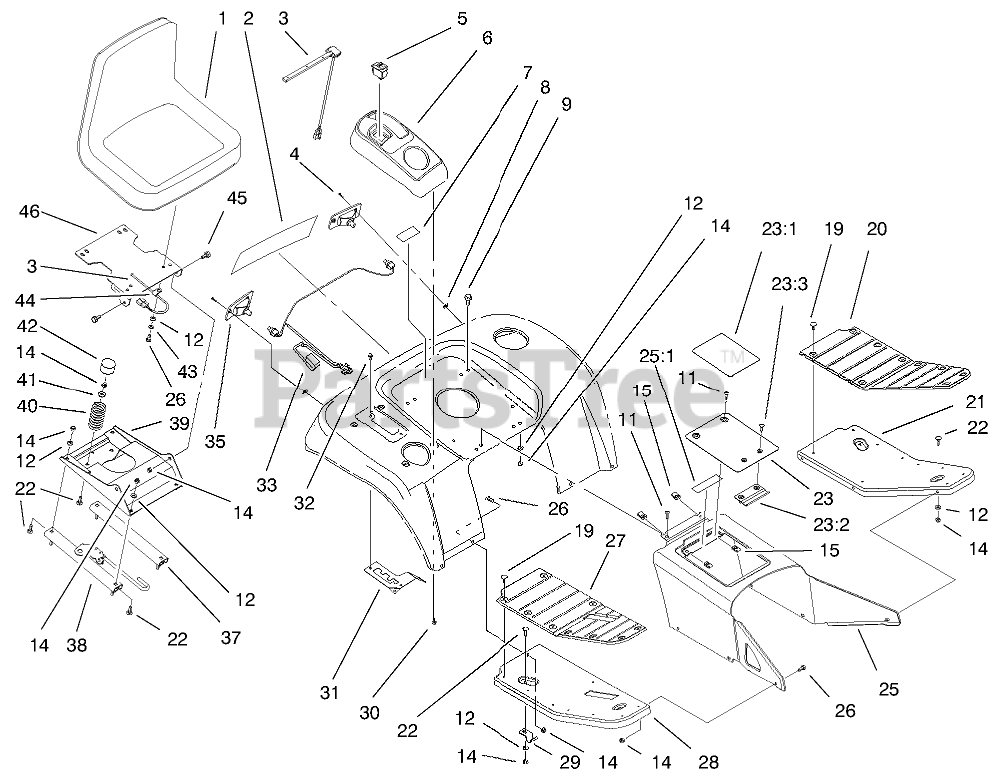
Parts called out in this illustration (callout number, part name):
1	SEAT
2	DECAL - FENDER
3	SWITCH-SEAT
4	SCREW-PPH
5	SWITCH-CRUISE
6	POD-CONTROL
7	DECAL - USA
8	NUT-SPEED
9	SCREW-HHF
11	SCREW-HH
12	WASHER-PLAIN
14	NUT-LOCK, NI
16	DECAL-DANGER
19	FASTENER-PANEL
20	PAD-FOOTREST, LH
21	FOOTREST-LH
22	SCREW-CARR
23	ASM - TUNNEL COVER TORO
23:1	DECAL - DANGER
23:2	RETAINER-COVER
23:4	SCREW-PPH
25	Tunnel ASM
25:1	DECAL-DANGER
26	SCREW-HH
27	PAD-FOOTREST, RH
28	FOOTREST-RH
29	BRACKET-FOOTREST
30	SCREW-HHFTF
31	Gate-Hi Lo Shift
32	SCREW-HWH
33	HARNESS - REAR
35	LAMP-TAILLIGHT
37	SLIDE-SLAVE, SEAT
38	SLIDE-LATCH, SEAT
39	Base-Seat
40	SPRING-COMPRESSION
41	BUSHING
42	CAP-SPRING, SEAT
43	WASHER-LOCK
44	CLAMP-R
45	BOLT-SHOULDER
46	Mount-Seat
